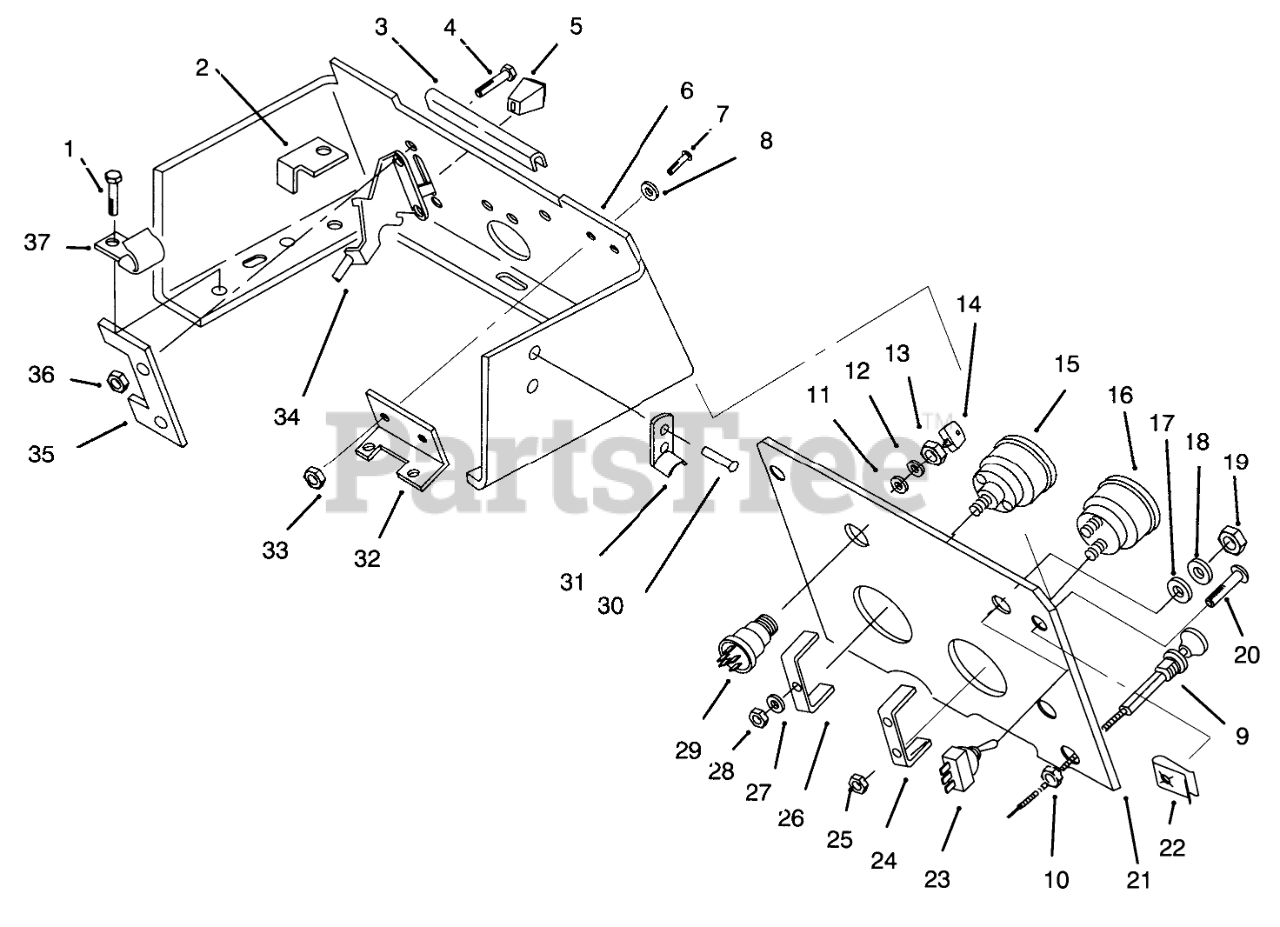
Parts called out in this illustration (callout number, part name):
1	SCREW
2	STOP-PTO
3	EDGING-CONSOLE
4	Screw
6	CONSOLE B
7	SCREW
8	Washer-Lock
9	CONTROL CHOKE
10	NUT-HEX PALNUT
11	Washer
12	LOCKWASHER
14	KEY-IGNITION
15	Meter-Hour (Incl. Ref.# 27-28)
16	Meter-Volt (Incl. Ref.# 24-25)
17	Washer
18	TAB-WASHER
20	Screw
21	Plate-Hood Stand
22	CLIP
23	Switch-Light (Incl. Ref. #17-19)
24	CLAMP-MOUNTING
25	HEX NUT 10-32 E.S.
26	CLAMP-HOUR METER
27	WASHER-LOCK
28	NUT-HEX
29	Switch-Ignition (Incl. Ref.#11-13)
30	POPRIVET 1/8X 1/8 BK
31	KEEPER-LATCH
32	BRACKET
33	Nut
34	CONTROL-THROTTLE
35	Washer
36	Nut
37	J-CLIP
